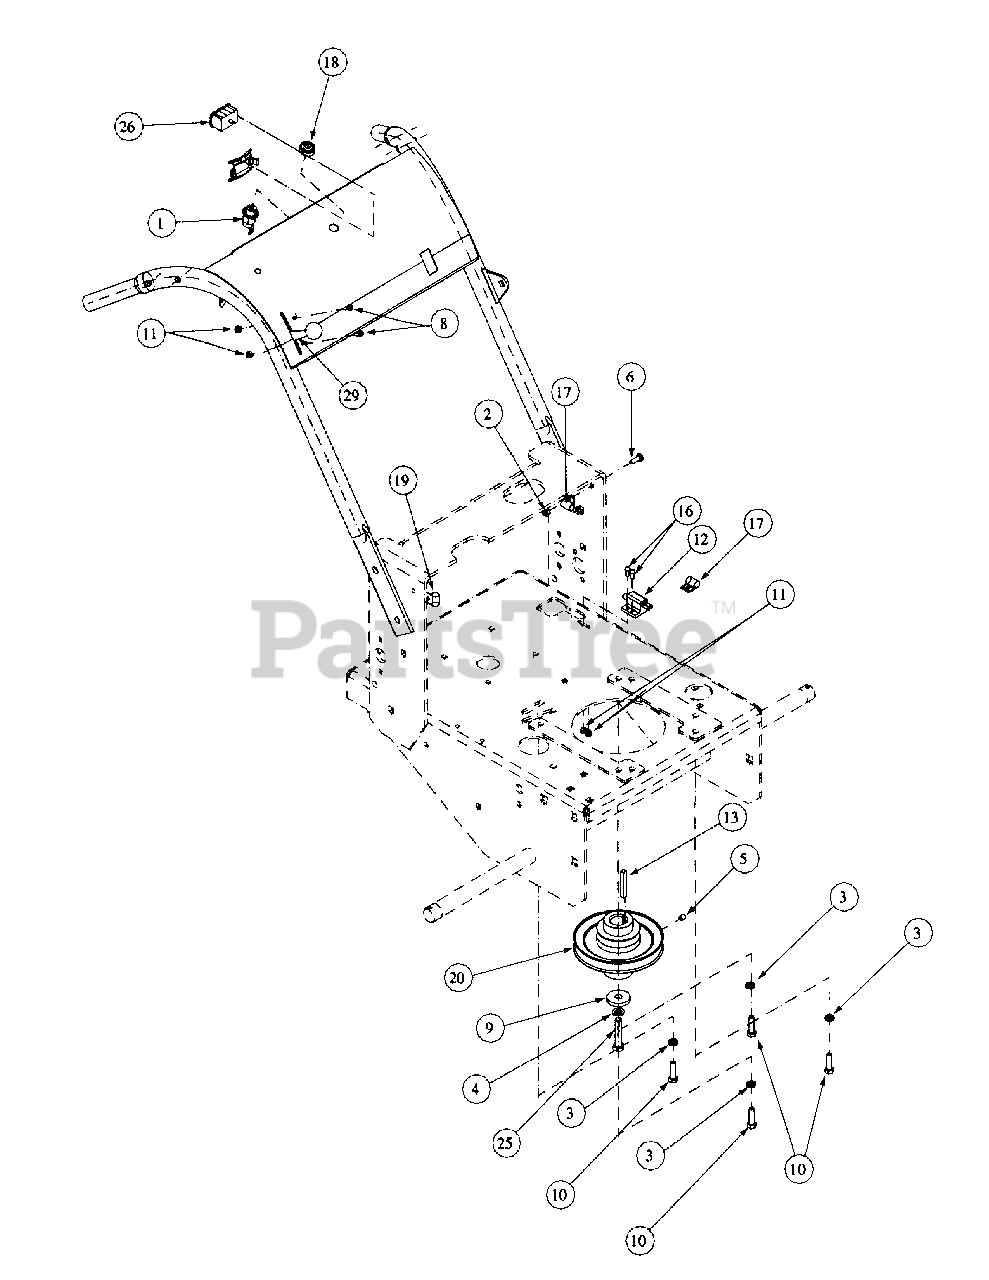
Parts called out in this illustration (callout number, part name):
1	Single Ignition ON/OFF Switch
2	Lock Nut, Nylon Insert, 1/4-20
3	Lock Washer, 5/16
4	Lock Washer, 7/16 Zinc
5	Nylock Screw, 5/16-18 x 3/8
6	Hex Cap Screw, 1/4-20, .75
8	Screw, Hex Washer, 10-32 x 1/2
9	Clutch Washer
10	Cap Screw, 1.25 x 30
11	Lock Nut, Nylon Insert, 10-32
12	Delta Switch
13	Key Stick, 1/4 x 1/4 x 2
14	Harness Wire
15	Hex Nut, Control Lock, 5/16-18
16	Machine Screw, 10-32 x 5/8
17	Support Clamp Tubing, 1/2"
18	Nut, w/Cap, 5/8-32, Ignition
19	Support Clamp, 3/8 OD
20	Double Pulley Gear
21	Bracket Muffler, Kawasaki
22	Belt
25	Capscrew, 7/16-20 x 2"
26	Hour Meter
27	Harness Hourmeter
28	Engine, 15HP Twin Kawasaki
29	Throttle Control, w/Detent, 47.25
